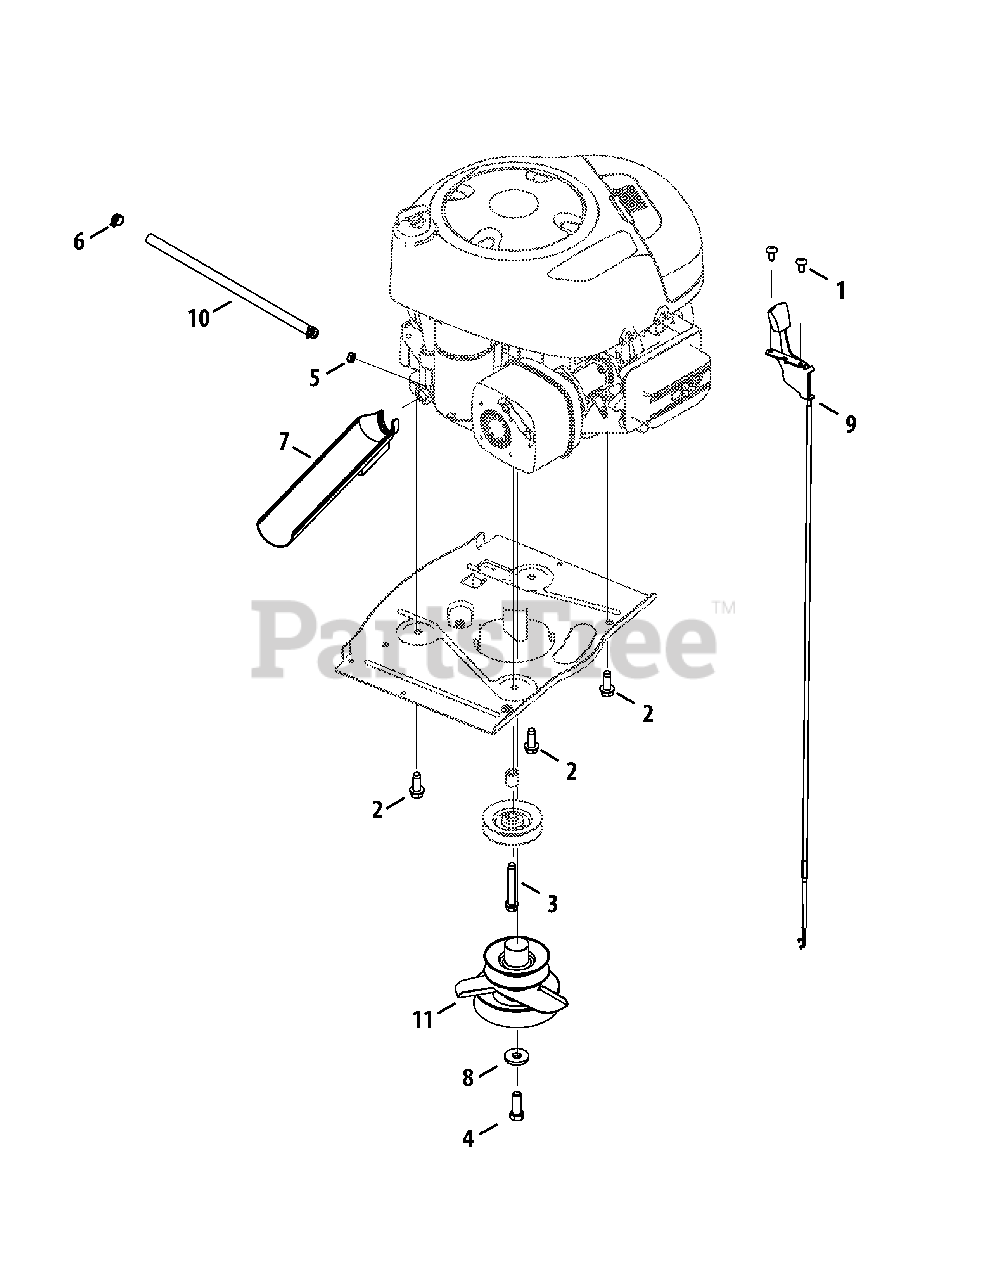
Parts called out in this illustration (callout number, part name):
1	Tap Screw, 1/4-20, 0.500
2	Tap Screw, 3/8-16, 1.000
3	Tap Screw, 3/8-16, 2.250
4	Hex Head Screw, 7/16-20 x 1.25
5	Sems Nut, 1/4-20
6	Hose Clamp, .490 DIA.
8	Flat Washer, .450 x 1.25 x .164
9	Throttle/Choke Cable 31 Lg.
10	Low Permeation Fuel Line, 1/4
11	Engine Pulley, 4.46 / 3.39
